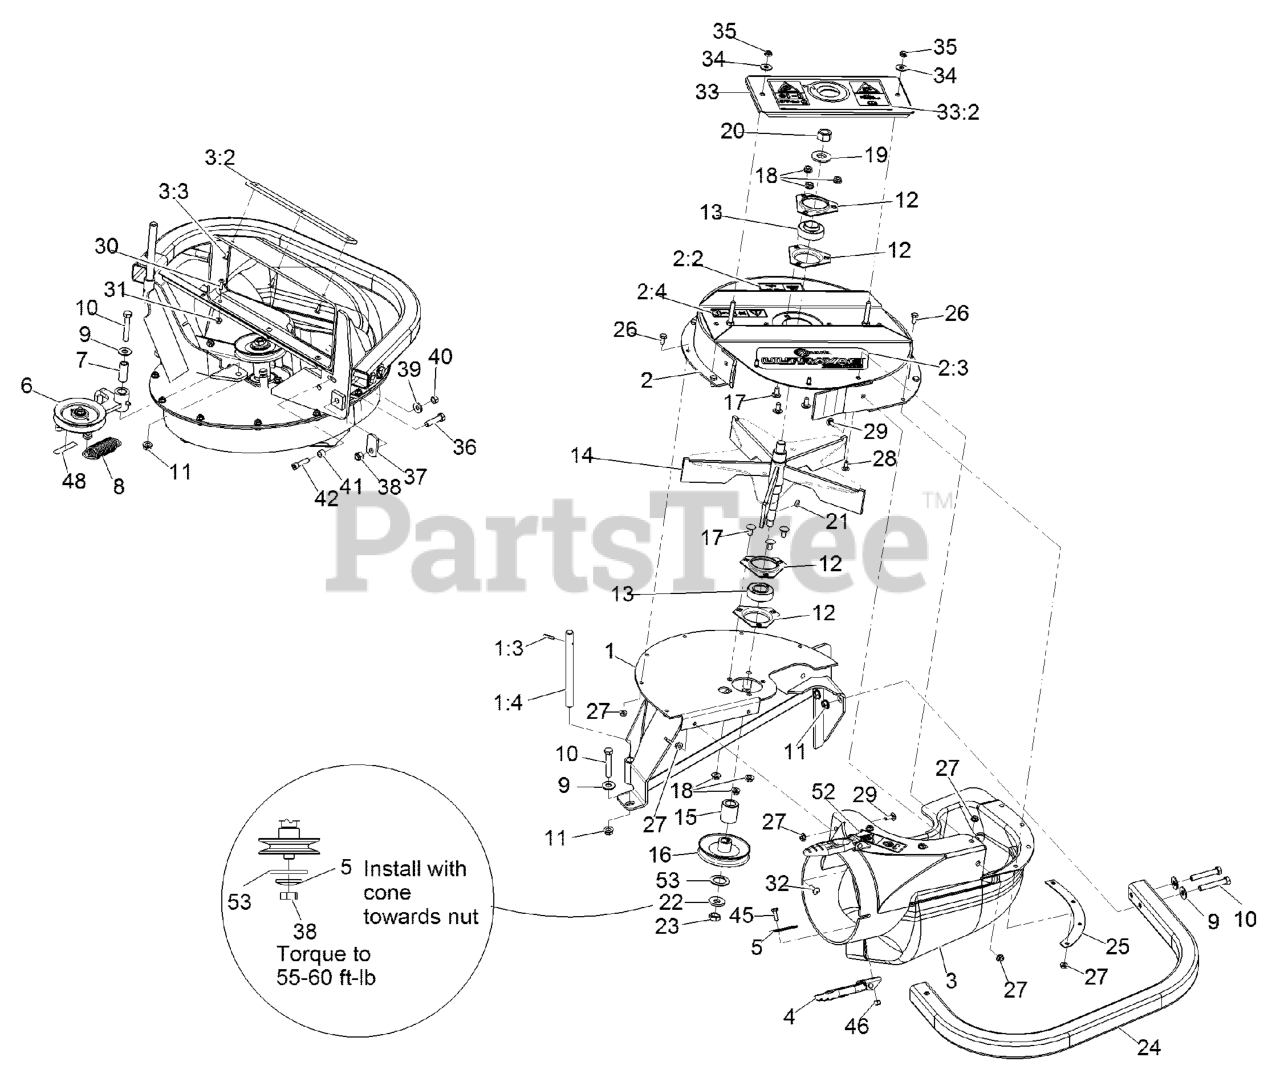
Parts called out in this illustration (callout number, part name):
1	WLD,FRAME LG BLOWER
1:3	PIN-ROLL
1:4	SHAFT-CATCHER, GRASS
2	ASM-UPPER HOUSING LARGE
2:2	DECAL-WARNING, TRACTION
2:3	Decal-Ultravac X-Series
2:4	DECAL-COVER, MISSING
3	ASM,BLOWER CHUTE LZ
3:2	PLATE,REINFORCEMENT LARGE
3:3	RIVET-BLIND
4	LATCH-RUBBER
5	PLATE-BACKING
6	ASM, Idler
7	BUSHING
8	SPRING-IDLER
9	WASHER-FLAT
10	SCREW-HH
11	NUT-HHF, WHIZ
12	HOUSING-FLANGE
13	BEARING
14	IMPELLER
16	SHEAVE
17	SCREW-CARR
19	WASHER-SPRING
20	NUT-HEX
21	KEY-WOODRUFF
22	WASHER-SPRING
23	NUT-JAM
25	PLATE-BACKING, BLOWER
26	SCREW-HH
28	SCREW-CARR
29	BOLT-CARR
30	SCREW-HEAD, TRUSS
33	ASM, BEARING COVER
33	COVER, BEARING
33:2	DECAL-WARNING, BLOWER
34	WASHER-FLAT
35	NUT-LOCK, NI
36	SCREW-HH
37	LATCH-CATCHER, GRASS
38	NUT-LOCK, NI
39	WASHER-SPRING
40	NUT-HEX
41	BUSHING, LOCATOR
42	SCREW-HSH
45	SCREW-HH
46	NUT-LOCK, NI
48	DECAL-WARNING
52	Decal-Blower-Impeller Hazard
53	WASHER-SPACER
